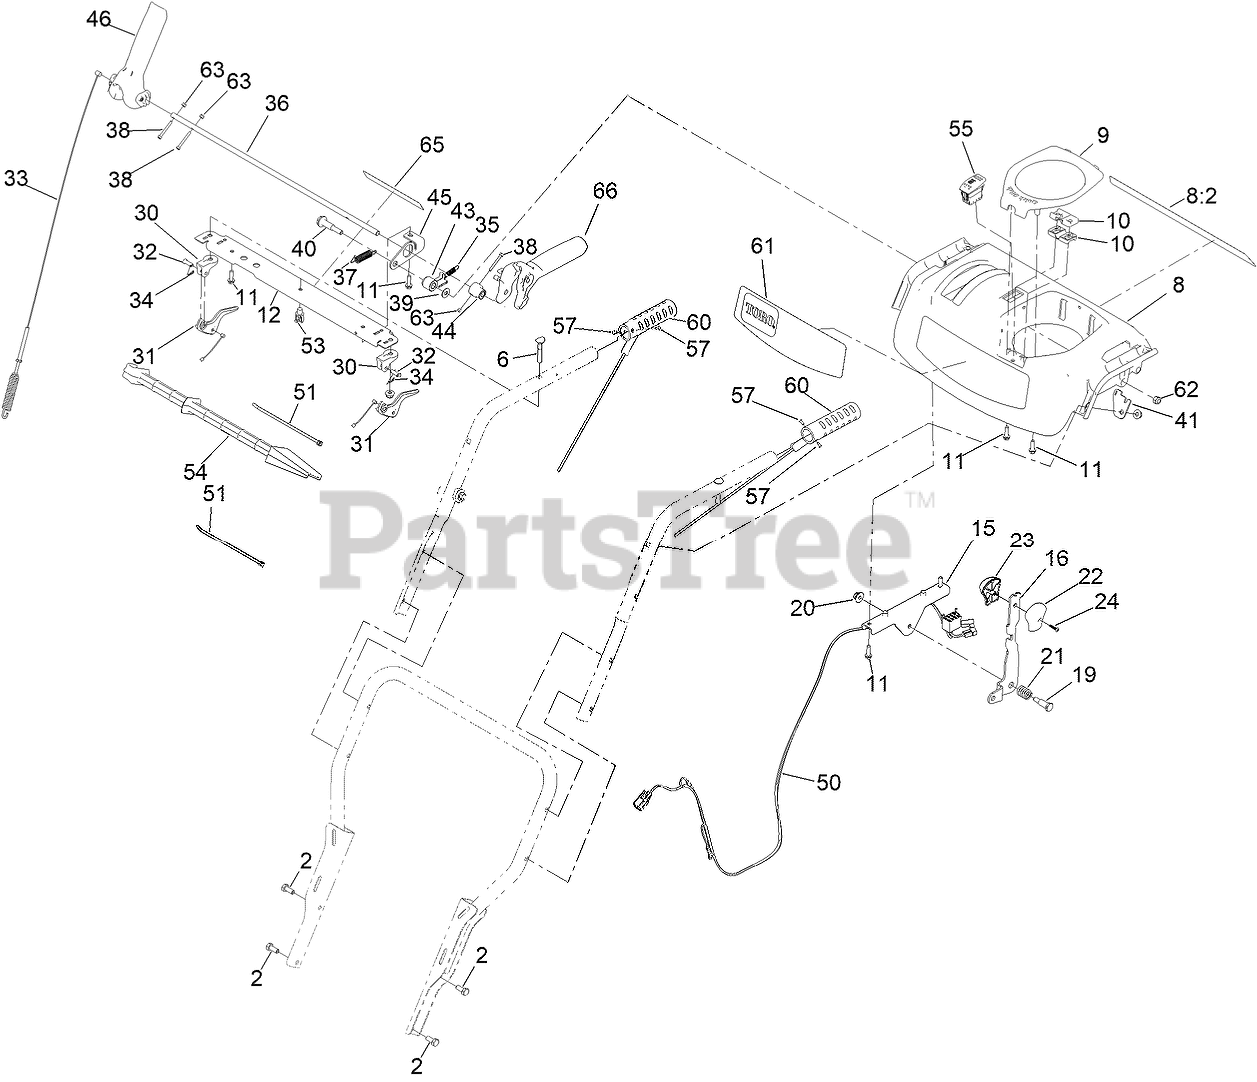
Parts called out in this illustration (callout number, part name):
2	SCREW-HH
6	SCREW-HANDLE
8	PANEL-CONTROL, ASSEMBLY
8:2	DECAL-SAFETY
9	COVER-QUICKSTICK
10	SUPPORT-ROD
11	SCREW-PLASTITE, HWH
12	BRACE-CONSOLE
15	BRACKET-SHIFT
16	SELECTOR-SPEED
19	SCREW-SHOULDER, HH
20	NUT-HF
21	SPRING-COMPRESSION
22	KNOB-SHIFT, LH
23	KNOB-SHIFT, RH
24	SCREW-PPH
30	MOUNT-LEVER, CLUTCH
31	LEVER-CLUTCH
32	PIN-CLEVIS
33	CABLE-AUGER
34	PIN-HAIR
35	SPRING-LOCKOUT, HANDLE
36	ROD-LOCKOUT
37	SPRING-RETURN, LEVER
38	SCREW-HSH,SPL
39	WASHER-FLAT
40	SCREW-SHOULDER
41	PLATE-SPRING
43	LATCH, LOCKOUT
44	CAM-LOCKOUT
45	BRACKET-INTERLOCK
46	LEVER-CONTROL
50	HARNESS-WIRE, LED AND HAND WARMERS
51	TIE-CABLE
53	CLIP-TIE
54	STICK-CLEANOUT
55	SWITCH-ROCKER, ON-NONE-OFF (HEATER)
57	RIVET-POP
60	RED HEATED GRIP
61	DECAL-CONSOLE, POWERMAX TRX HD 1432
62	NUT-HEX
63	NUT-LOCK ROHS
65	DECAL-HYDRO
66	LEVER-CONTROL
